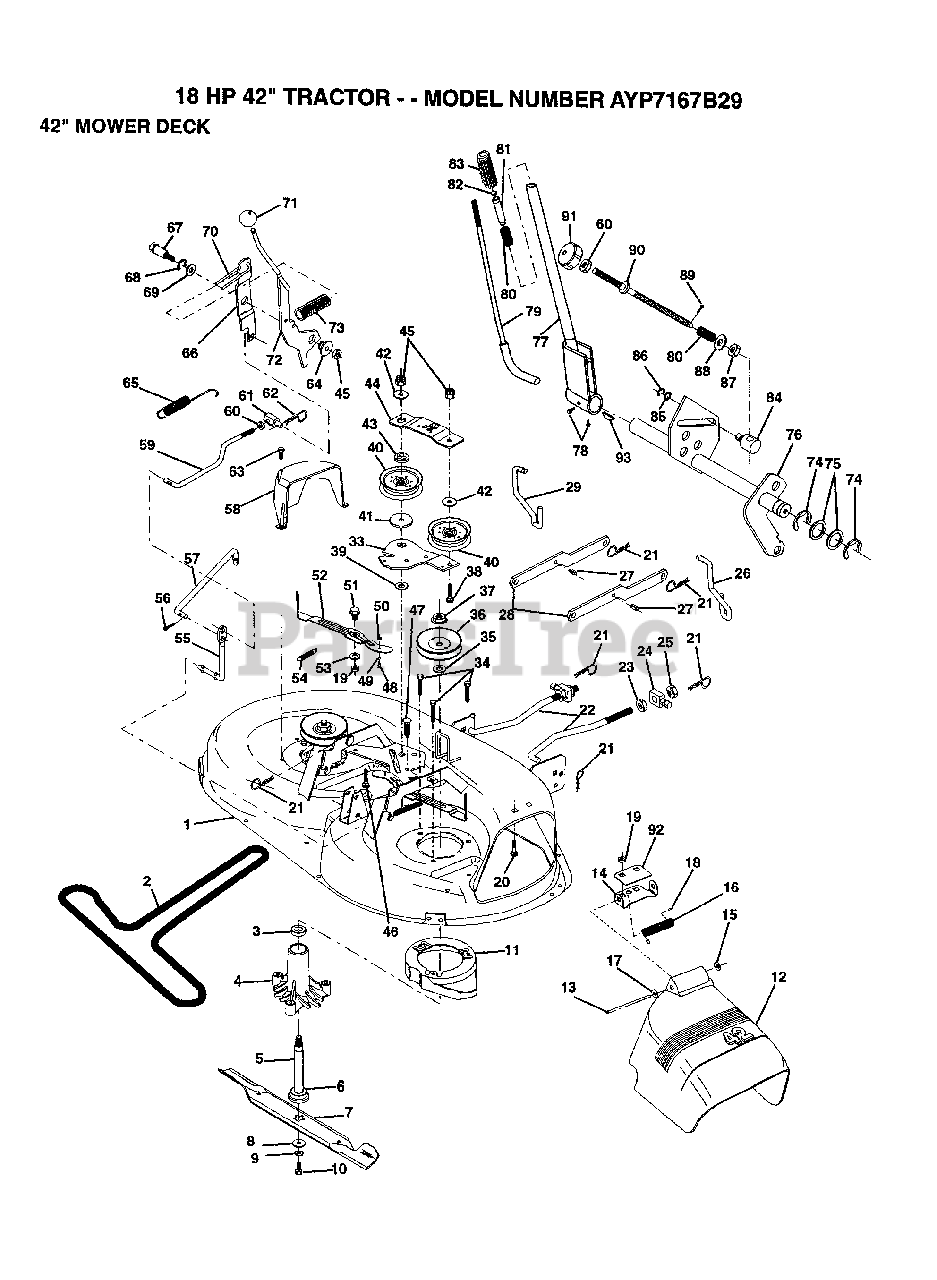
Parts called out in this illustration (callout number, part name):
2	BELT-V.92.4.MWR
3	BEARING
4	HSG ASM MANDREL
6	BEARING.BALL
8	WASHER BLADE
10	BLADE BOLT
12	DEFLECTOR.SHIELD
13	HINGE ROD
14	DEFLECTOR BRKT
15	NUT PUSH M
16	SPRING TORSION
17	WASHER
18	CAP-SLEEVE LT
20	BOLT
22	LINK.FRONT
23	NUT
24	TRUNION
25	NUT.LK.W/WSH.1/2.
26	LIFT LINK RH
27	"PIN,SPRING"
29	LINK LIFT LH
33	IDLER ARM
35	WASHER
38	BOLT
39	HARDENED WASHER
40	FLAT IDLER PULLEY
41	SPACER RETAINER
42	WASHER GT
43	RETAINER SPACER
44	IDLER ARM STIFF
46	BOLT CARRIAGE
47	XMAS TREE FASTNER
48	SHOULDER BOLT
50	LOCKNUT
52	BRAKE PAD ARM ASM
53	HARD SMALL WASHER
54	SPRING EXTENSION
55	PIVOT ROD
57	CLUTCH ROD SECOND
60	NUT
61	TRUNION
62	RETAINER M
63	SCREW LT
64	BUSHING
65	RETURN SPRING
66	CLUTCH ARM SECOND
67	SHOULDER BOLT
68	RING
69	WASHER
70	SPRING KEEPER
74	E-RING
75	WASHER
83	GRIP
84	TRUNION LT
85	WASHER
86	KLIP RING
87	NUT T
88	WASHER
90	ROD LIFT LT
92	STIFFENER BRKT
